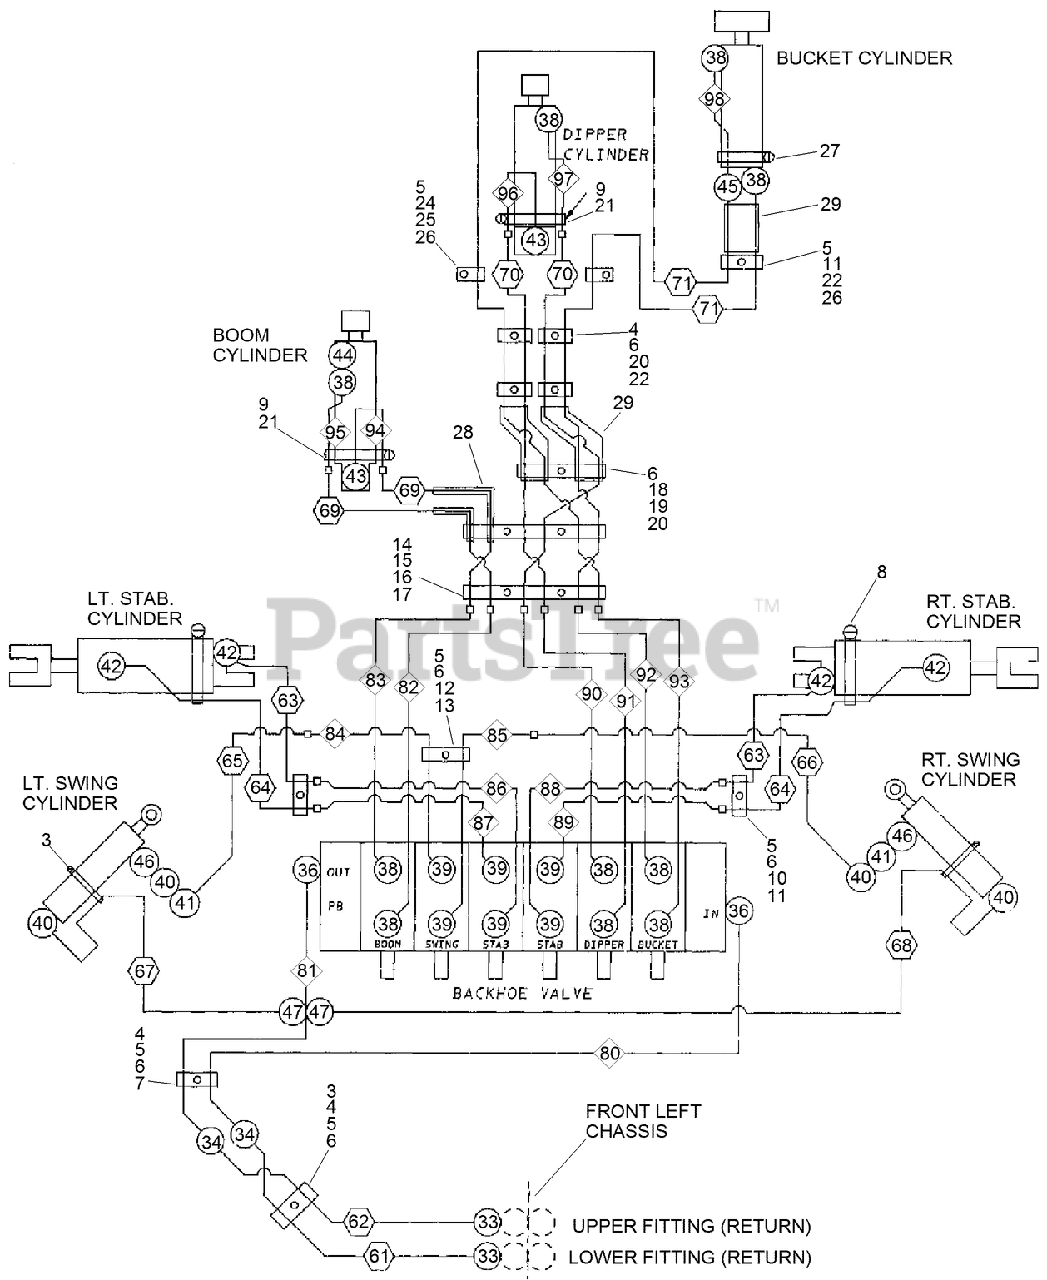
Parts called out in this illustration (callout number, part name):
3	RETAINER - Hose
4	BOLT-Hex Hd .375 x 1.75 GR5 ZND
5	NUT-SQUARE
6	WASHER-FLAT
7	RETAINER - 3/4 Tube
8	CLAMP-Hose Type F #72
9	SADDLE-SUPPORT, TUBE
10	CLAMP-TUBE
11	BOLT-hex, 3/8 NC x 1-1/2 inch
12	RETAINER - Tube
13	SCREW-HH
14	STRAP-ANGLE
15	BOLT - 5/16 x 3-1/4
16	NUT-Prev Trq 5/16 GRA CAD NONDIR
17	WASHER-Flat 5/16 HT
18	CLAMP-HOSE, RETAINER
19	SCREW-HH
20	NUT
21	CLAMP-HOSE
22	RETAINER-HOSE
24	RETAINER - Hose
25	SCREW-HH
26	WASHER-Spring Lock, Reg 3/8 ZND
27	CLAMP-Hose #56
28	SLEEVE - Hose Retaining, Protective, Hose
29	SLEEVE - Hose Protector (Dia 1-3/4)
33	FITTING-ELBOW, 90
36	ELBOW-90 Adj 37FL 3/4 Tube
38	CONNECTOR-Str Thd 5/8, 37FL-ORB 5/8
39	CONNECTOR
40	ELBOW-90 DEG (ADJUSTABLE 37 DEG)
41	ORIFICE - Plate, One-Way (0.0935 in Dia)
42	ELBOW-90 Adj 37FL, 3/8 x 1/2 Tube
43	ELBOW-90 Adj 37FL 5/8 Tube
44	ORIFICE-FLOATING
45	FITTING-UNION
46	WASHER-0.219 x 0.500 x 0.049 in CST ZND
47	CONNECTOR - 9/16 MJ x 9/16 MJ Str
61	HOSE - 5/8 x 775mm, 100R2, 1-1/16 FJ Ends
62	ASM-Hose
63	HOSE - 533 mm (21 inch) Long, Upper Right-hand Port of Selector Valve to Rod End of Plow Lift Cylinder
64	HOSE - 1/4 x 215mm, 100R1, 9/16 MJ x 9/16 FJ
65	HOSE - 1/4 x 12mm, 100R1, 9/16 MJ x 9/16 FJ
66	HOSE - 1/4 x 15mm, 100R1, 9/16 MJ x 9/16 FJ
67	HOSE - 3/8 x 508mm, 100R1, 9/16 FJ x 9/16 90 Deg
68	HOSE - 3/8 x 876mm, 100R1, 9/16 FJ x 9/16 90 Deg
69	HOSE - 1/2 x 910mm, MEGA-FLEX 78 MJ Ends
70	HOSE - 1/2 x 180mm, MEGA-FLEX 7/8 MJ Ends
71	HOSE - 1/2 x 2830mm, MEGA-FLEX 7/8 MJ x 1/8 FJ
80	TUBE - Valve Inlet (3/4 OD)
81	TUBE - Valve Return (3/4 OD)
82	TUBE - Valve, Boom Head (5/8 OD)
83	TUBE - Valve, Boom Rod (5/8 OD)
84	TUBE - Valve, LH Swing (3/8 OD)
85	TUBE - Valve, RH Swing (3/8 OD)
86	TUBE - Valve, LH Stab Head (3/8 OD)
87	TUBE - Valve, LH Stab Rod (3/8 OD)
88	TUBE - Valve, RH Stab Head (3/8 OD)
89	TUBE - Valve, RH Stab Rod (3/8 OD)
90	TUBE - Valve, Dipper Head (5/8 OD)
91	TUBE - Valve, Dipper Rod (5/8 OD)
92	TUBE - Valve, Bucket Head (5/8 OD)
93	TUBE - Valve, Bucket Rod (5/8 OD)
94	TUBE - Boom Cylinder Head (5/8 OD)
95	TUBE - Boom Cylinder Rod (5/8 OD)
96	TUBE - Dipper Cylinder Head (5/8 OD)
97	TUBE - Dipper Cylinder Rod (5/8 OD)
98	TUBE - Bucket Cylinder Rod (5/8 OD)
